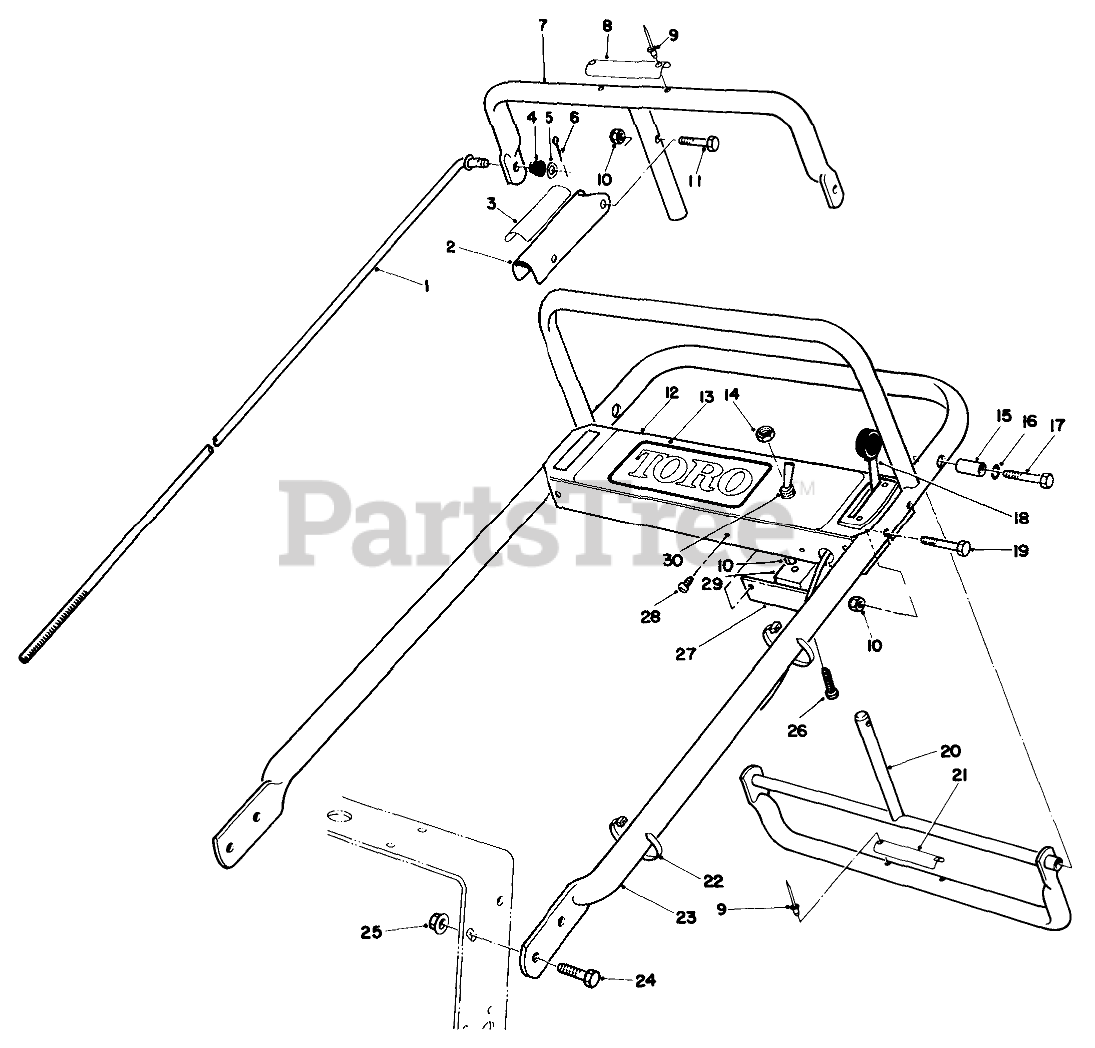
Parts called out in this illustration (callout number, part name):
1	ROD-CONTROL
2	Lever-Parking Brake
3	DECAL-LEVER, PARKING
4	GROMMET-RUBBER
5	WASHER-PLAIN
6	PIN-COTTER
7	Bar-Control
8	DECAL-CONTROL BAR
9	RIVET-BLIND
10	NUT-LOCK, NI
11	SCREW-SHH
12	Panel-Control
13	JLO PANEL DECAL
14	NUT
15	PIVOT-SPACER
16	WASHER-LOCK
17	SCREW-HH
18	THROTTLE-CONTROL
19	SCREW-SHH
20	Control-Pivot
21	DECAL-REVERSE HANDLE
22	TIE-CABLE
23	HANDLE-UPPER
24	SCREW-HHF
25	NUT-HF
26	SCREW-HWH
27	PANEL-BOTTOM
28	SCREW-HWHTF
29	RECTIFIER-BRIDGE
30	Switch
